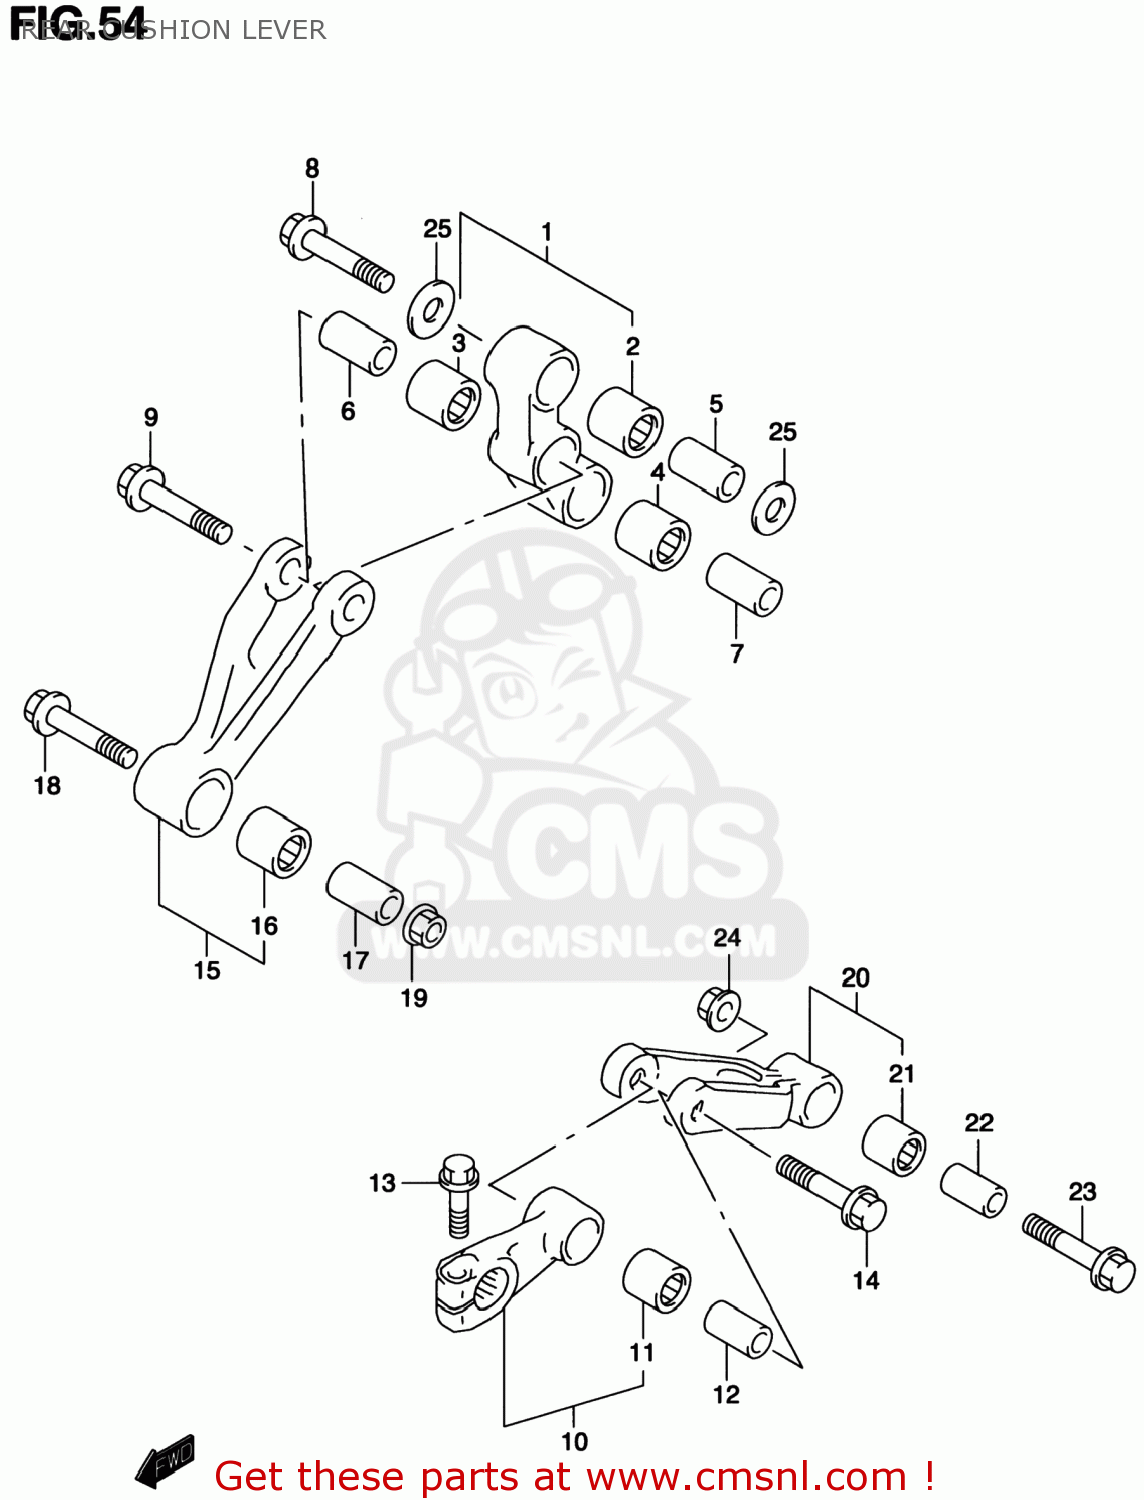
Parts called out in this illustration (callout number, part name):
1	LEVER SET,REAR CUSHION
2	BEARING(20X27X30)
3	BEARING(20X27X32)
4	BEARING(17X24X20)
5	SPACER,RR CUSHION LEVER FR
6	SPACER,RR CUSHION LEVER FR
7	SPACER,RR CUSHION LEVER RR
8	BOLT,RR CUSHION LEVER FR
9	BOLT,CUSHION LEVER FR
10	ARM SET,REAR CUSHION
11	BEARING(14X20X25)
12	SPACER,RR CUSH ARM
13	BOLT(8X31)
14	BOLT,RR CUSHION ROD UPR
15	ROD SET,REAR CUSHION,RIGHT
16	BEARING(20X27X32)
17	SPACER,RR CUSHION LEVER FR
18	BOLT,RR CUSHION LEVER FR
19	NUT 12MM
20	ROD SET,RR CUSHION,L
21	BEARING(14X20X25)
22	SPACER,RR CUSH ARM
23	BOLT,REAR SHOCK ABSORBER
24	NUT
25	SHIM(20X30X0.5)
